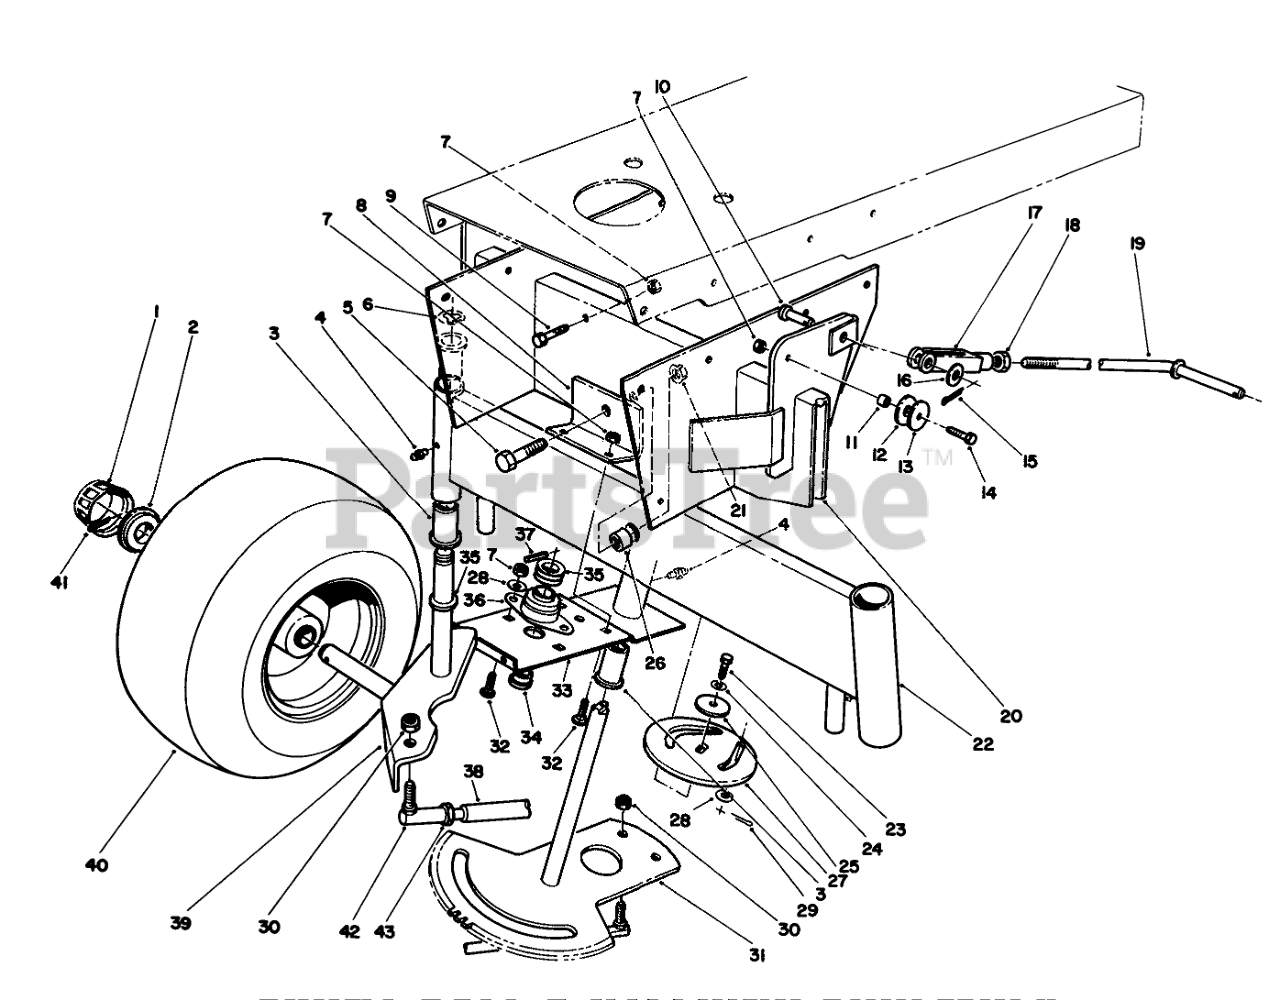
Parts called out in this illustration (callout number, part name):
1	CAP-HUB
2	FRONT WHEEL SPACER
3	BUSHING PM
4	GREASE FITTING
5	SCREW-HH
6	E-RING
7	NUT-LOCK, NI
8	SPINDLE SPROCKET BRKTB
9	SCREW-HH
10	PIN-CLEVIS
11	FLOOR SPACER
12	WASHER-RUBBER
13	WASHER-FLAT
14	SCREW-HH
15	PIN-COTTER
16	WASHER-FLAT
18	NUT-JAM
19	FRONT LINK
20	Support-Front Axle
21	NUT-HF
22	Axle-Front (Incl. Ref. #3 & 4)
23	SCREW-HH
24	WASHER-LOCK
25	SPACER
26	SPACER-AXLE, FRONT
27	PLATE-PULL ROD
28	WASHER-PLAIN
29	PIN-COTTER
30	NUT-LOCK
31	STEERING RACK WA B
32	SCREW-CARR
33	Spindle-Steering Rack (Incl. Ref. #3 & 4)
34	BEARING-FLANGE
35	WASHER-THRUST
36	BUSHING
37	PIN-ROLL, SLOTTED
38	Tie Rod-Steering (Incl. Ref. #42 & 43)
39	R/H SPINDLE WA
40	Tire & Wheel Assy-Front
41	PIN-COTTER
42	JOINT-BALL, RH THREADED
43	NUT-HJ
